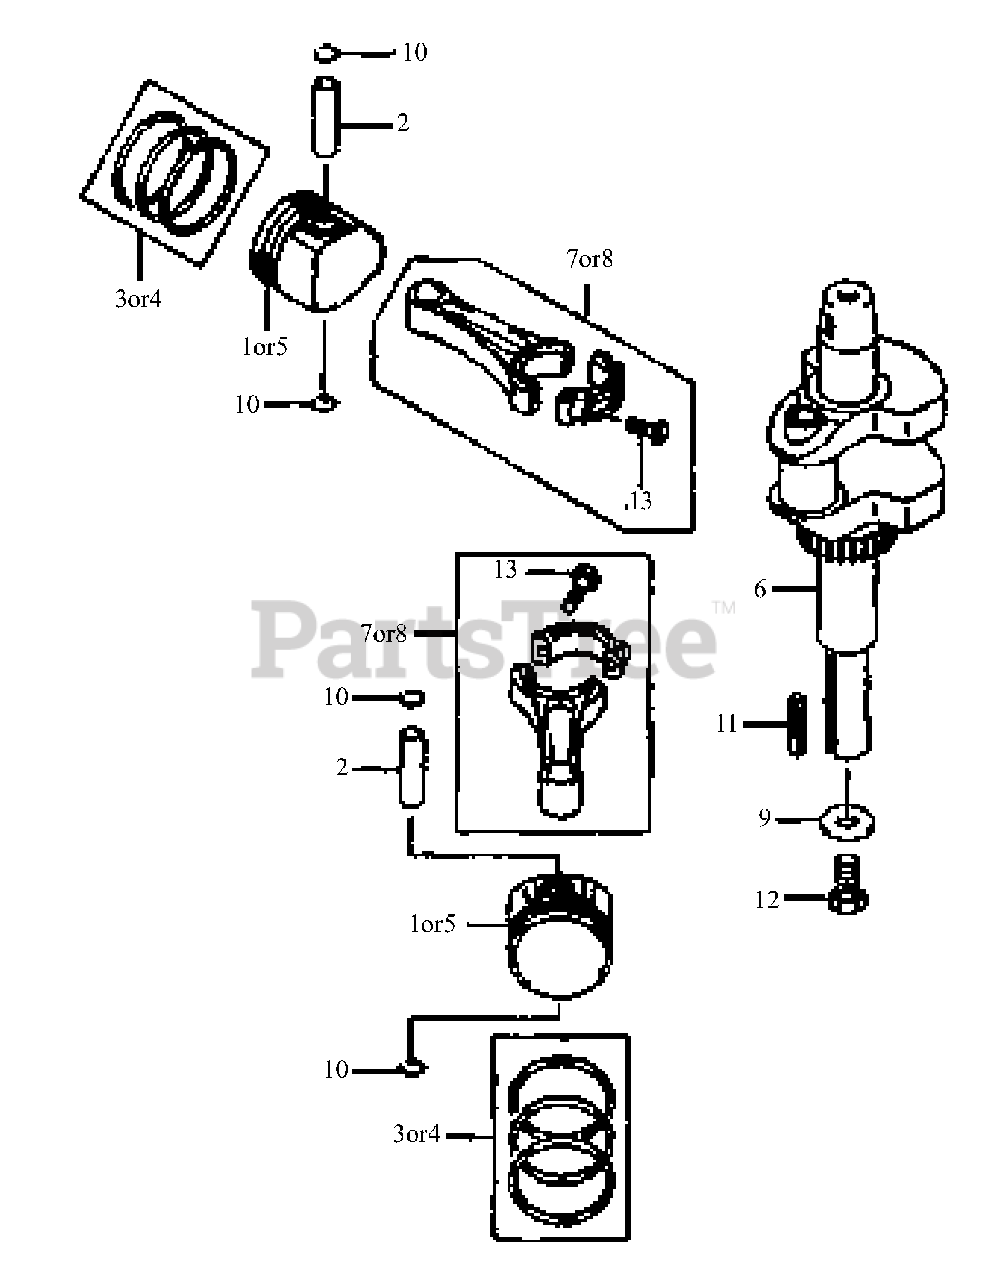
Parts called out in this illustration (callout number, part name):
1	Piston, Engine
3	Ring, Set Piston
4	Ring, Set Piston 0.050
5	Piston, Engine 0.050
6	Crankshaft, Comp.
7	Rod, Connecting u/s 0.050
8	Rod, Connecting Std
9	Washer 12.5x32x3.2
10	Ring, Snap
12	Bolt 7/16-20 unf
13	Bolt Flange
